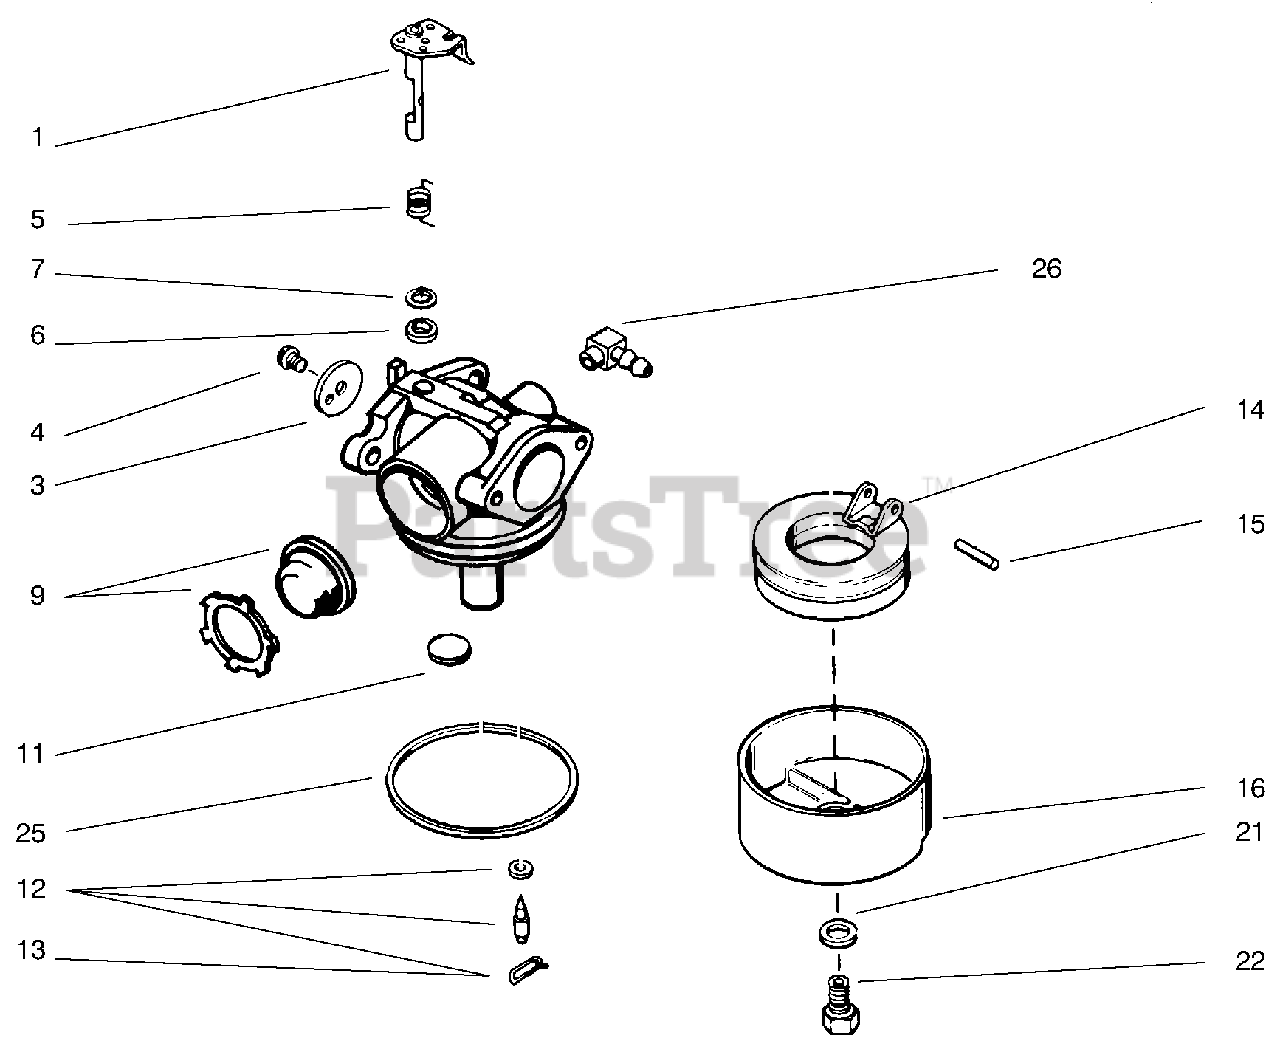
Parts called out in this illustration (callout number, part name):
1	Shaft And Lever Assembly
3	Shutter-Throttle
5	Spring-Return
6	Seal-Dust
7	Washer--Flat
9	Primer-Bulb & Retainer
12	Needle Seat & Clip Assy (Incl. Ref. #13)
14	Float-Carburetor
15	Shaft-Float
16	Bowl-Float
21	Gasket-Bowl
22	Nut-Bowl
25	Gasket-Bowl
26	Fitting-Inlet
